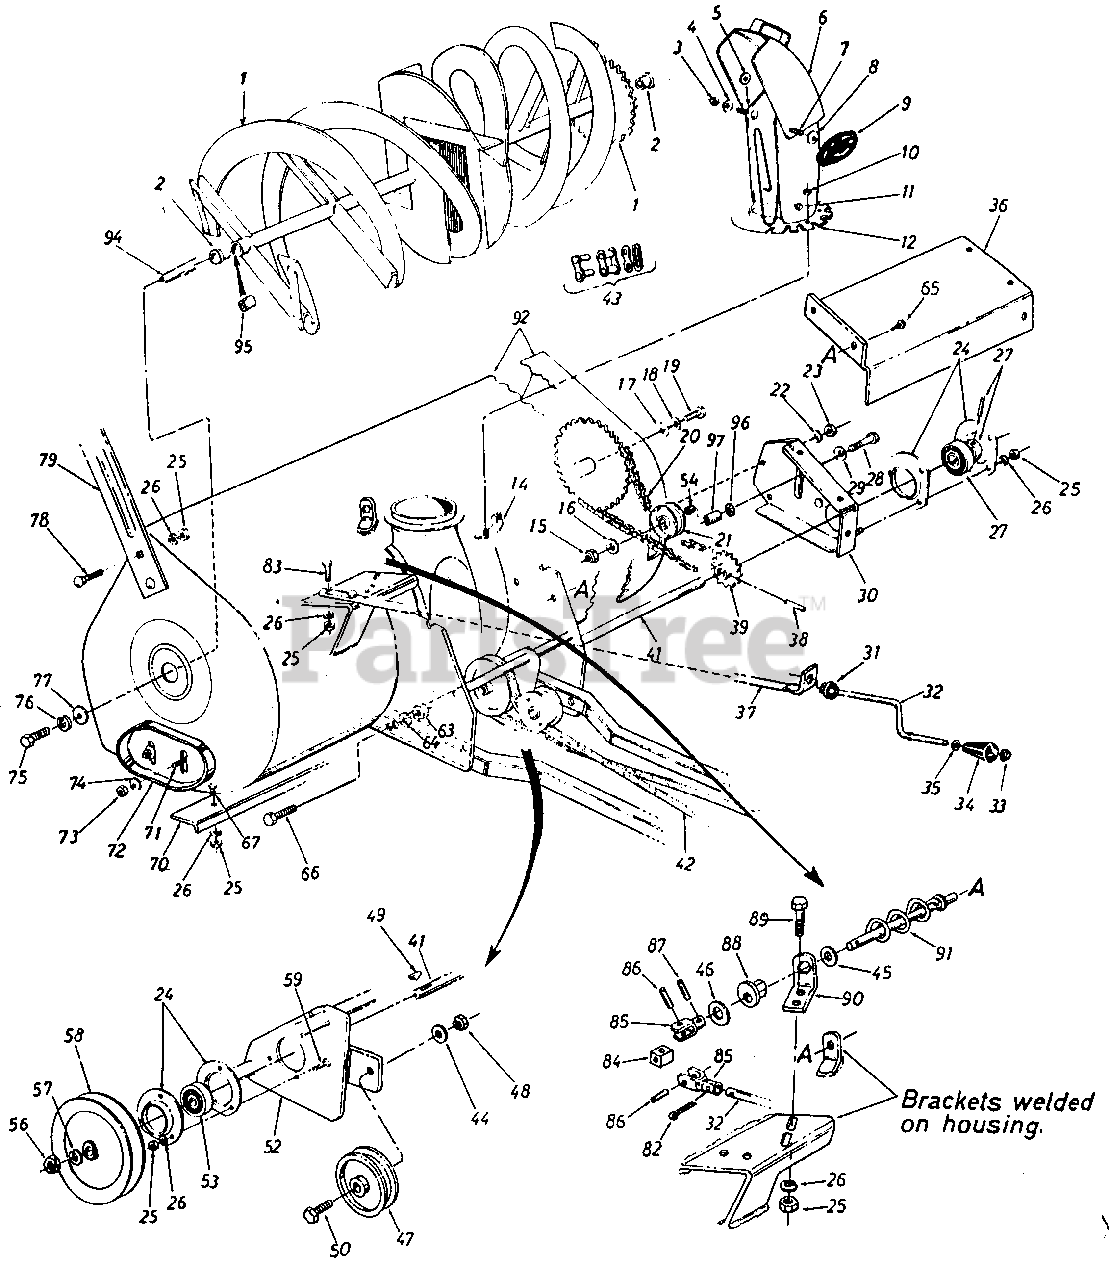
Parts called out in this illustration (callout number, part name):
1	ROTOR ASSY.
2	BEARING, FLANGE
3	NUT, 5/16-18 LOCK
4	WASHER, 3/8 BLELLEVILLE
5	WASHER, 3/8 FLAT
6	CHUTE ASSY. TOP
7	BOLT, 5/16-18 X .62 CRG
8	WASHER, 3/8 BLELLEVILLE
9	KNOB, HAND
10	NUT, 1/4-20 LOCK
11	CAP, PUSH-.188 DIA ROD
12	CHUTE ASSY.
14	KEPPER ASSY. CHUTE FLANGE
15	NUT, 3/8-16 LOCK
16	WASHER, FLAT
17	WASHER, FLAT
18	WASHER, BELLEVILLE
19	BOLT, 1/2-13 X 1
20	CHAIN (77 LINKS OF NO.420 1/2" PITCH)
21	IDLER, PLASTIC (2.00 IN. DIA)
22	WASHER, 1/4 LOCK
23	NUT, 1/4-20
24	HOUSING, BEARING
25	NUT, 5/16-18
26	WASHER, 5/16 LOCK
27	BEARING, SELF-ALIGNING
28	BOLT, 3/8-16 X 1.75
29	WASHER, 3/8 BLELLEVILLE
30	GUARD ASSY, CHAIN
31	GROMMET
32	GRANK, CHUTE (.375 DIA X 39 IN. LONG)
33	NUT, 3/8 PUSH-ON
34	KNOB, 3/8 DIA HOLE
35	WASHER, FLAT
36	COVER, DRIVE SHAFT
39	SPROCKET ASSY, 14T
41	SHAFT, DRIVE
43	LINK, MASTER (FOR NO. 420 CHAIN)
44	WASHER, 3/8 LOCK
45	WASHER, .385 X .62
46	WASHER, .390 X 1.50
47	IDLER W/FLANGES, FLAT
48	NUT, 3/8-26 JAM
49	KEY, NO.61 HI-PRO
50	BOLT, 3/8-16 X 1.50
52	HOUSING, ROTOR
53	BEARING, SELF-ALIGNING
54	SLEEVE, BEARING (.50 ID)
56	NUT, 3/4-10
57	WASHER, 3/4 LOCK
58	PULLEY, V (.750 ID X 6.00 OD)
59	BOLT, 5/16-18 X .75 SEMS
63	NUT, 1/2-20 LOCK
64	WASHER, 1/2 LOCK
65	SCREW, 1/4-20 X .50 HEX-WASHER-HD TAP
66	BOLT, 1/2-20 X 1.25
67	BOLT, 5/16-18 X .62 CRG
72	SHOW, SKID
73	NUT, 3/8-16
74	WASHER, 3/8 BLELLEVILLE
75	BOLT, 1/2-13 X 1
76	WASHER, 1/2 BELLEVILLE
77	WASHER, 3/8 FLAT
78	BOLT, 5/16-18 X .62 CRG
79	CUTTER, DRIFT
82	PIN, 3/32 COT.
83	BOLT, 5/16-18 X 1.50
84	BLOCK, JOINT
85	BRACKET ASSY. JOINT
86	PIN, 3/16 X .75 ROLL
87	PIN, 1/8 X .75 ROLL
88	BUSHING, .385 ID HEX.
89	BOLT, 5/16-18 X .62 CRG
90	BRACKET, CHUTE CRANK
91	CRANK ASSY. CHUTE
92	HOUSING ASSY. ROTOR
94	AXLE ASSY. ROTOR
95	BEARING, SLEEVE
96	WASHER, FLAT
97	SPACER, IDLER
